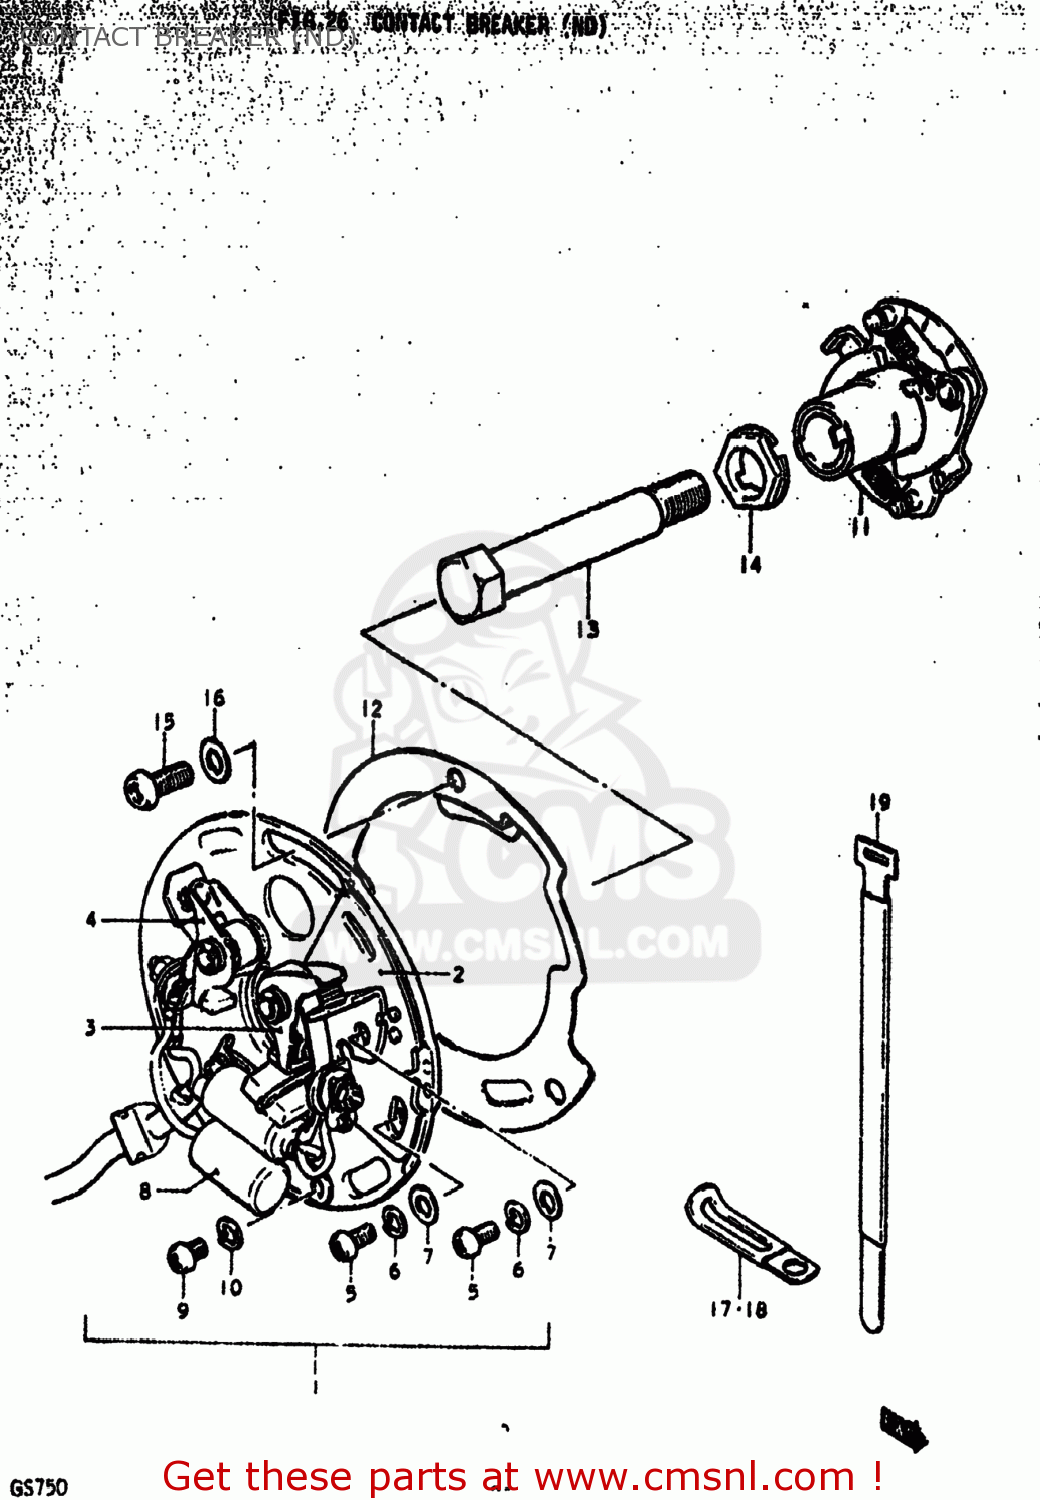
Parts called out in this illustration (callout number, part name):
1	BREAKER ASSEMBLY,CONTACT
2	PLATE,CONTACT POINT
3	POINT ASSY,R
4	POINT ASSY,L
5	SCREW(4X10)
6	LOCK WASHER
7	WASHER
8	CONDENSER
9	SCREW
10	LOCK WASHER
11	GOVERNOR ASSEMBLY
12	PLATE,IGNITION TIMING
13	BOLT
14	WASHER
15	SCREW(5X12)
16	WASHER 5MM
17	CLAMP L:35
18	CLAMP
19	CLAMP
